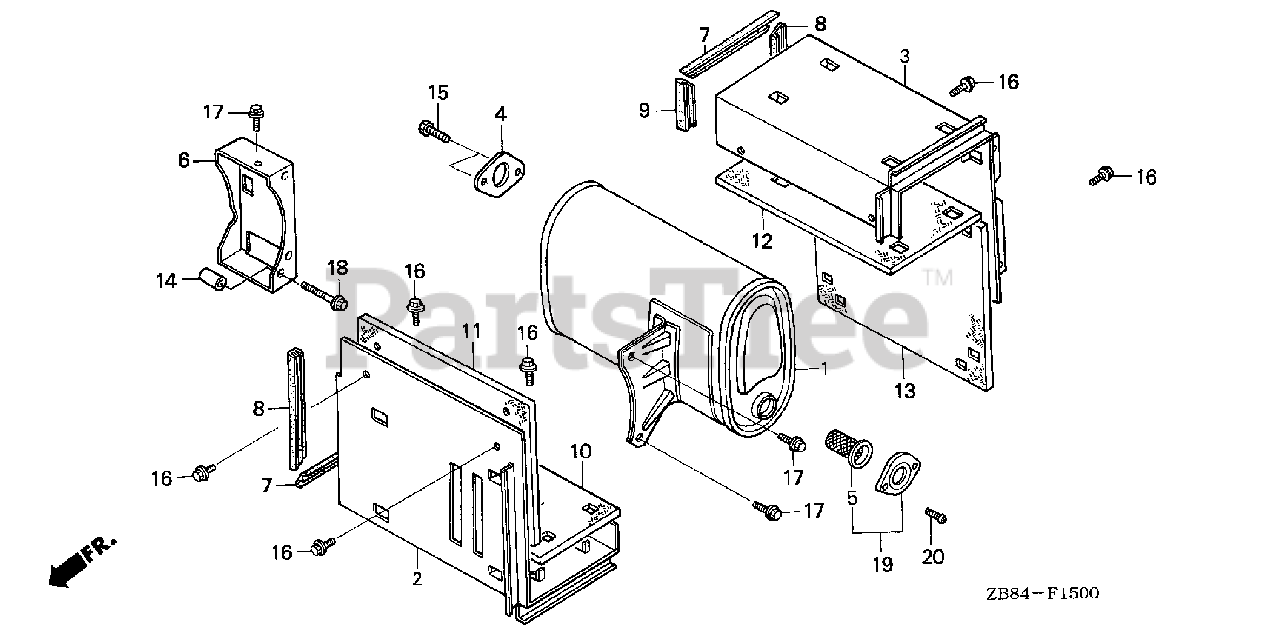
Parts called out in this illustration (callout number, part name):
2	DUCT, MUFFLER (LOWER)
3	DUCT, MUFFLER (UPPER)
4	GASKET, EX. PIPE
5	ARRESTER, SPARK
6	STAY, MUFFLER
7	SEAL, MUFFLER DUCT (A)
8	SEAL, MUFFLER DUCT (B)
9	SEAL, MUFFLER DUCT (C)
10	INSULATOR A, MUFFLER DUCT (LOWER)
11	INSULATOR B, MUFFLER DUCT (LOWER)
12	INSULATOR A, MUFFLER DUCT (UPPER)
13	INSULATOR B, MUFFLER DUCT (UPPER)
14	COLLAR, MUFFLER STAY
15	BOLT, HEX. (8X28)
16	BOLT, FLANGE (6X12)
17	BOLT, FLANGE (8X16)
18	BOLT, FLANGE (8X40)
19	ARRESTER SET, SPARK
20	SCREW, PAN (6X10)
